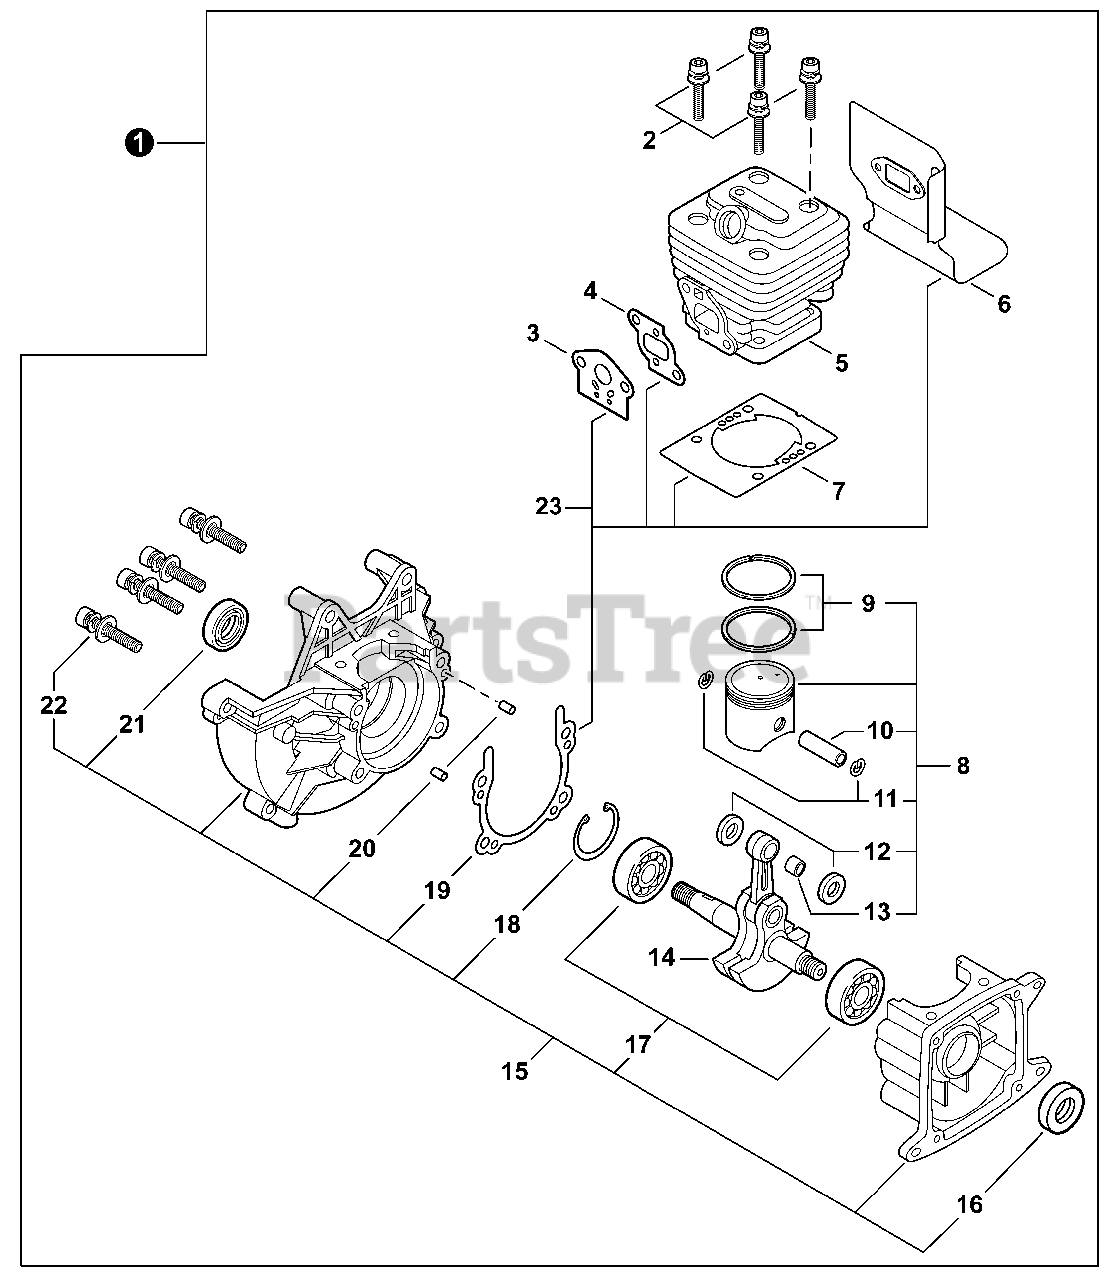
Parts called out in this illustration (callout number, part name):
1	SHORT BLOCK
2	BOLT 5×22
3	GASKET, CARBURETOR
4	GASKET, INTAKE
5	CYLINDER
6	HEAT SHIELD, EXHAUST
7	GASKET, CYLINDER
8	PISTON KIT
9	RING, PISTON
10	PIN, PISTON 8
11	RING, SNAP
12	WASHER, THRUST
13	BEARING, NEEDLE 8
14	CRANKSHAFT ASSY
15	CRANKCASE ASSY
16	SEAL, OIL 12
17	BEARING, BALL 6001
18	RING, SNAP 28
19	GASKET, CRANKCASE
20	PIN, LOCATING 4×8
21	SEAL, OIL 12
22	BOLT 5×25
23	GASKET KIT
